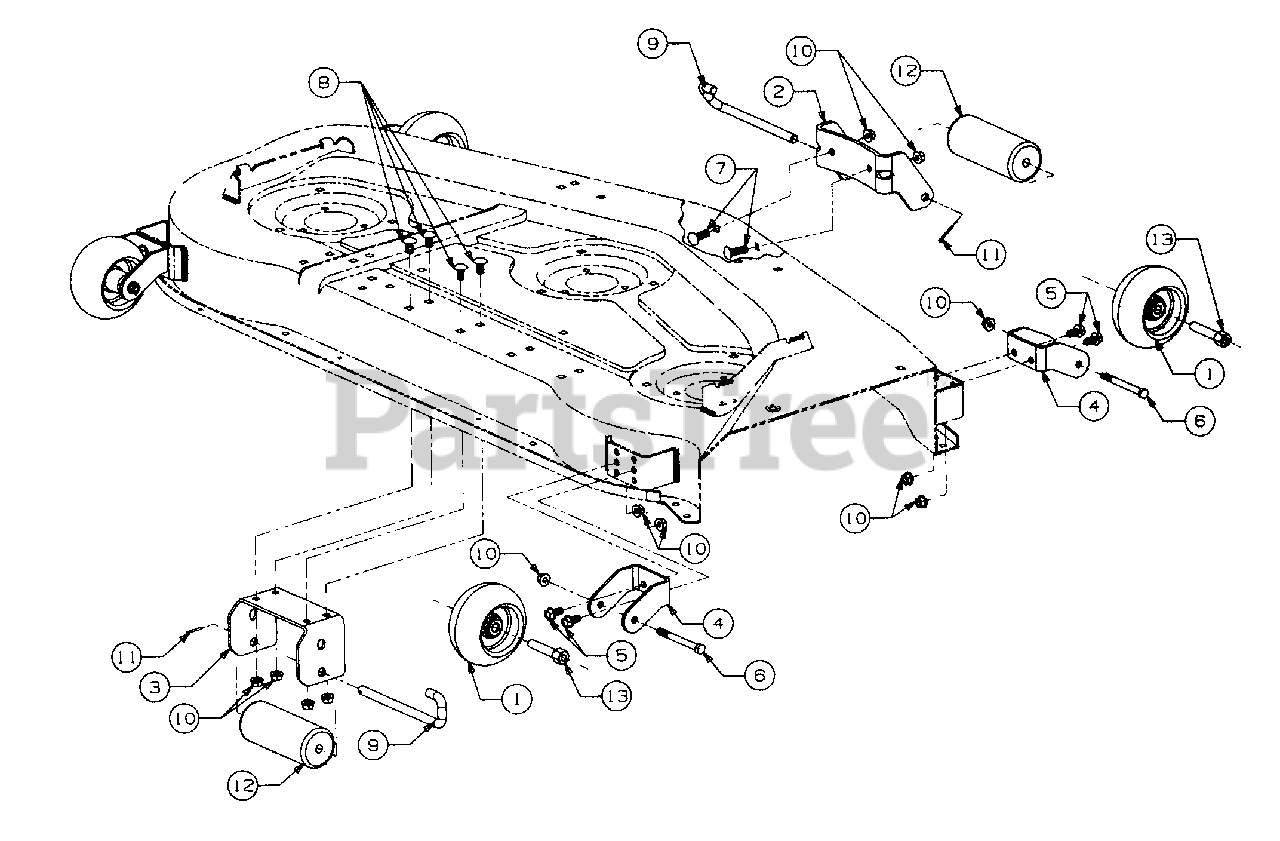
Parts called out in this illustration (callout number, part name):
1	Ball Wheel/Roller Kit (Includes Ref No. 1 thru 13)
6	Screw,HexCap, 3/8-16 X 3.75 Lg
7	Bolt, Carriage, 3/8-16 X 1.25 Lg GR5
8	Bolt, Sht Nk Carriage, 3/8-16 X .75 Lg GR5
9	Pin, Roller, 1/2 Dia X 7.31 Lg
10	Nut, Hex Flanged Lock, 3/8-16
11	Pin, Cotter, 1/8 Dia X 1.0 Lg
13	Spacer, Deck Wheel
